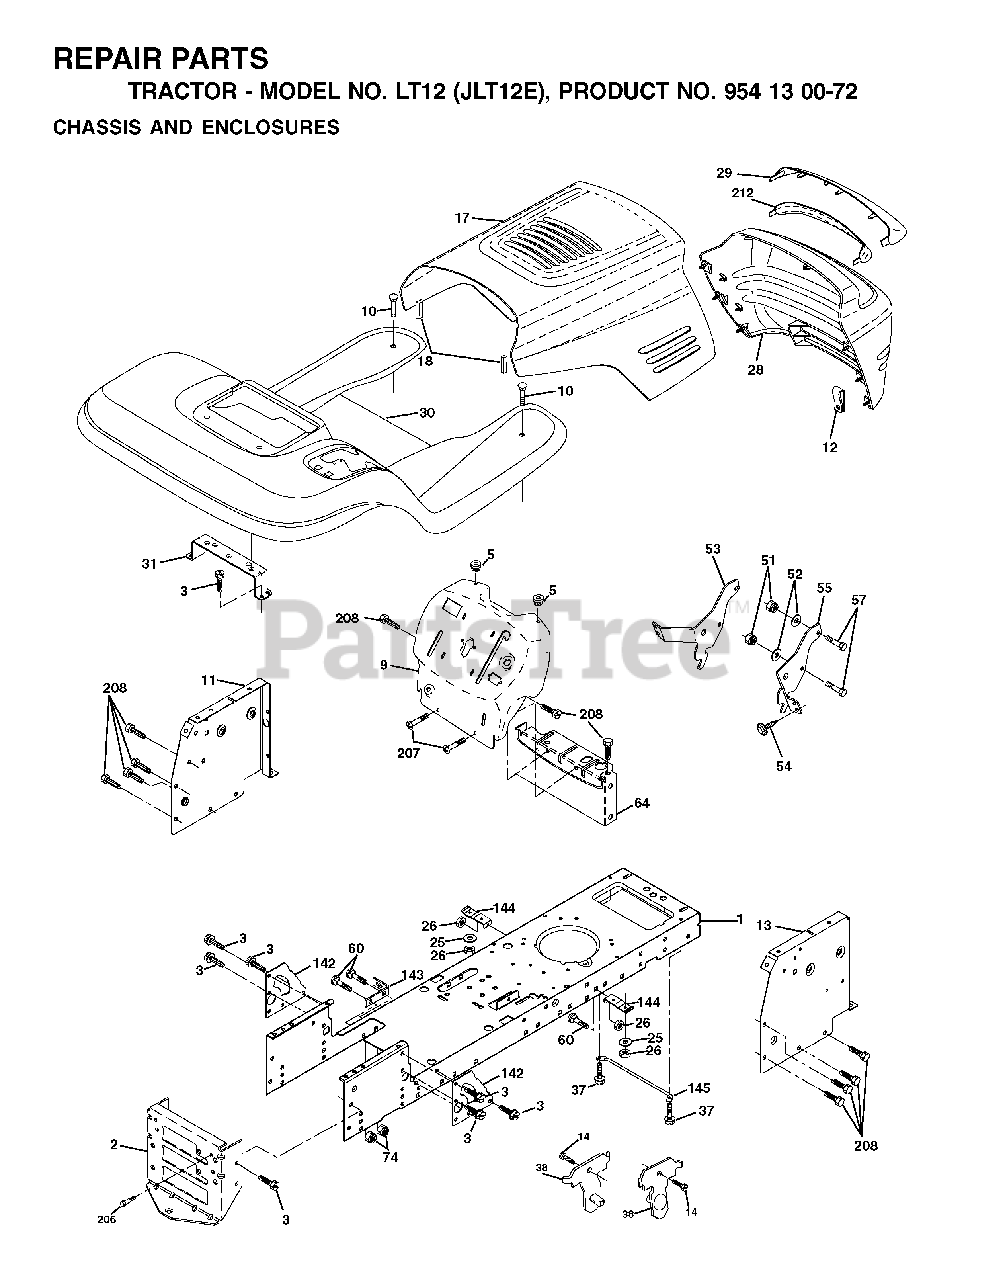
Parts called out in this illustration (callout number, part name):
1	CHASSIS STAMPING
2	DRAWBAR, 12GA
3	SCREW 3/8-16X3/4
5	BUMPER.RUBBER.HOOD
10	BOLT D
11	PANEL.DASH.LH.LTX
13	PANEL DASH RH
18	BUMPER HOOD T
25	WASHER
26	NUT
38	BRACKET.ASM.PIVOT.MOWER.REAR
51	LOCKNUT
57	BOLT
64	DASH LOWER
74	LOCKNUT
142	PLATE REINFORCEMENT
143	BRACKET, SWAY BAR
144	BRKT, FOOT REST
145	ROD PIVOT CHASSIS/HOOD
206	SHOULDER BOLT 5/16-18TT
207	SCREW, 5/16-18 X 1/2
208	SCREW 3/8-16X1/2
